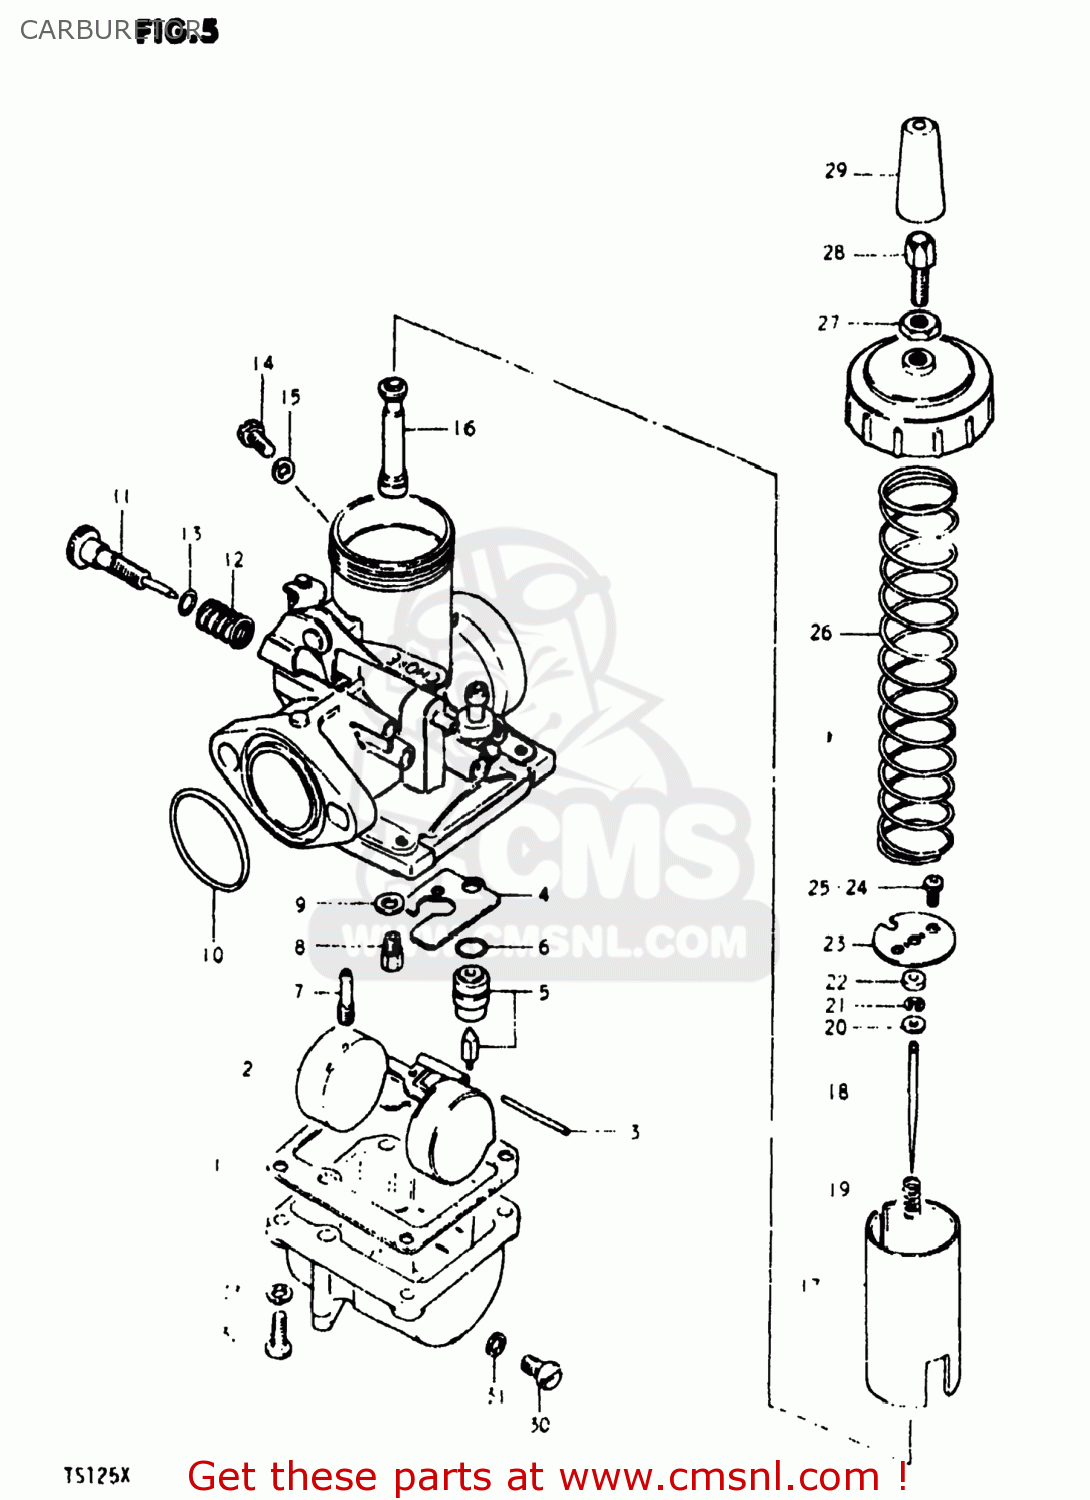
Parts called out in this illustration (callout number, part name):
1	GASKET,FLOAT CHAMBER (NAS)
2	FLOAT
3	PIN,FLOAT
4	PLATE
5	VALVE ASSY,NEEDLE
6	GASKET,VALVE SEAT (NAS)
7	JET,PILOT(17.5)
8	JET,MAIN(120)
9	WASHER
10	O RING
11	SCREW,THROTTLE STOP
12	SPRING,PILOT
13	O-RING
14	BOLT
15	GASKET,THRO VALVE INSPECTION (NAS)
16	JET,NEEDLE
17	VALVE,THROTTLE
18	NEEDLE JET
19	SPRING
20	WASHER,JET NEEDLE
21	CLIP
22	RING
23	PLATE,THROTTLE VALVE
24	LOCK WASHER
25	SCREW
26	SPRING,THROTTLE VALVE
27	NUT
28	ADJUSTER,CABLE
29	CAP
30	PLUG
31	GASKET,DRAIN,PLUG (NAS)
32	SCREW
33	LOCK WASHER
